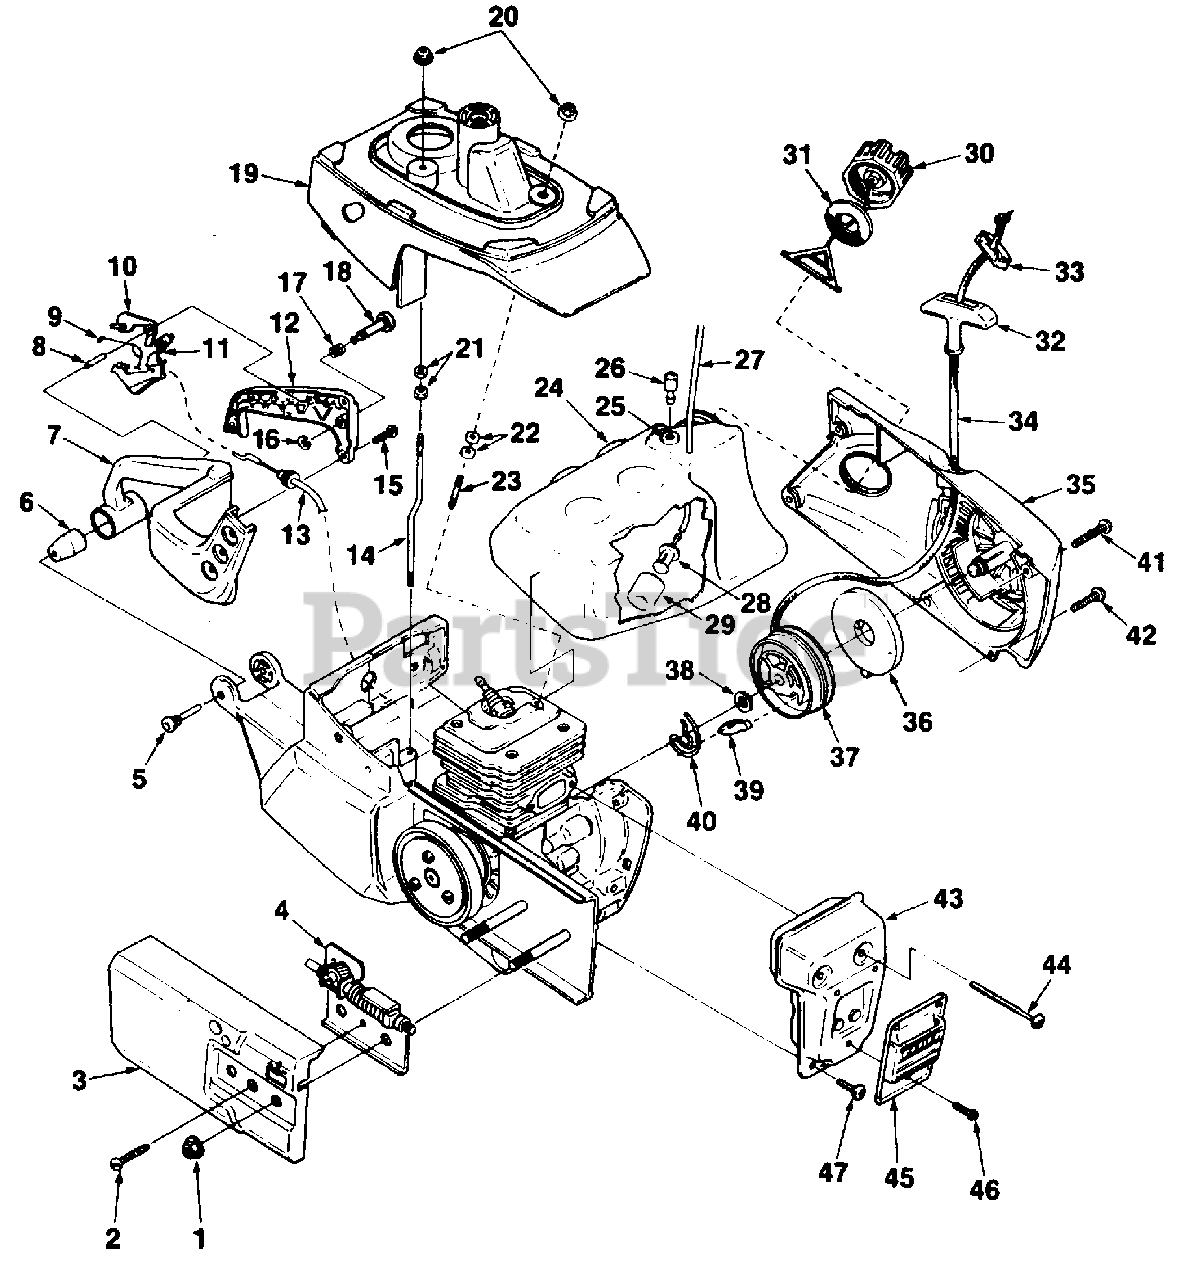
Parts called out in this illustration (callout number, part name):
1	NUT- Hex flange (5/1-18)
2	SCREW- Taptite (8-32 x 5/8")
3	COVER- Clutch
4	GEAR KIT
5	PIN- Isolator
6	ISOLATOR- Vibration
7	HANDLE- Rear
8	PIN- Trigger
9	SPRING- Throttle
10	LOCK- Trigger
11	TRIGGER
12	COVER- Handle
13	CABLE- Throttle
14	STUD- Offset (10-24)
15	SCREW- Plastite (8-16 x 5/8")
16	RING- Retaining
17	SPRING- Compression
18	PIN- Throttle lock
19	COVER- Cylinder
20	NUT- Hex concical
21	NUT- Hex
23	STUD (10-24 x 1.06")
24	TANK- Fuel
25	GROMMET
26	FILTER SLEEVE (Complete)
27	TUBING- Rubber
28	FILTER- Fuel
29	FILTER- Fuel
30	CAP- Tank (w/retainer)
31	GASKET- Tank cap
32	GRIP- Starter (w/insert)
33	INSERT- Rope ret.
34	ROPE- Starter
35	HOUSING- Starter (w/bushing)
36	SPRING & CONTAINER
37	PULLEY ASSEMBLY
40	CLIP
41	SCREW- Truss hd. (10-24 x 1 1/4")
42	SCREW- Truss hd. (10-24 x 3/4")
43	MUFFLER
44	SCREW- Truss hd. (10-24 x 21/2")
45	CAP- Muffler
46	SCREW- Mach. hex hd. (8-32 x 1/2")
47	SCREW- Torx (10-24 x 3/4"
